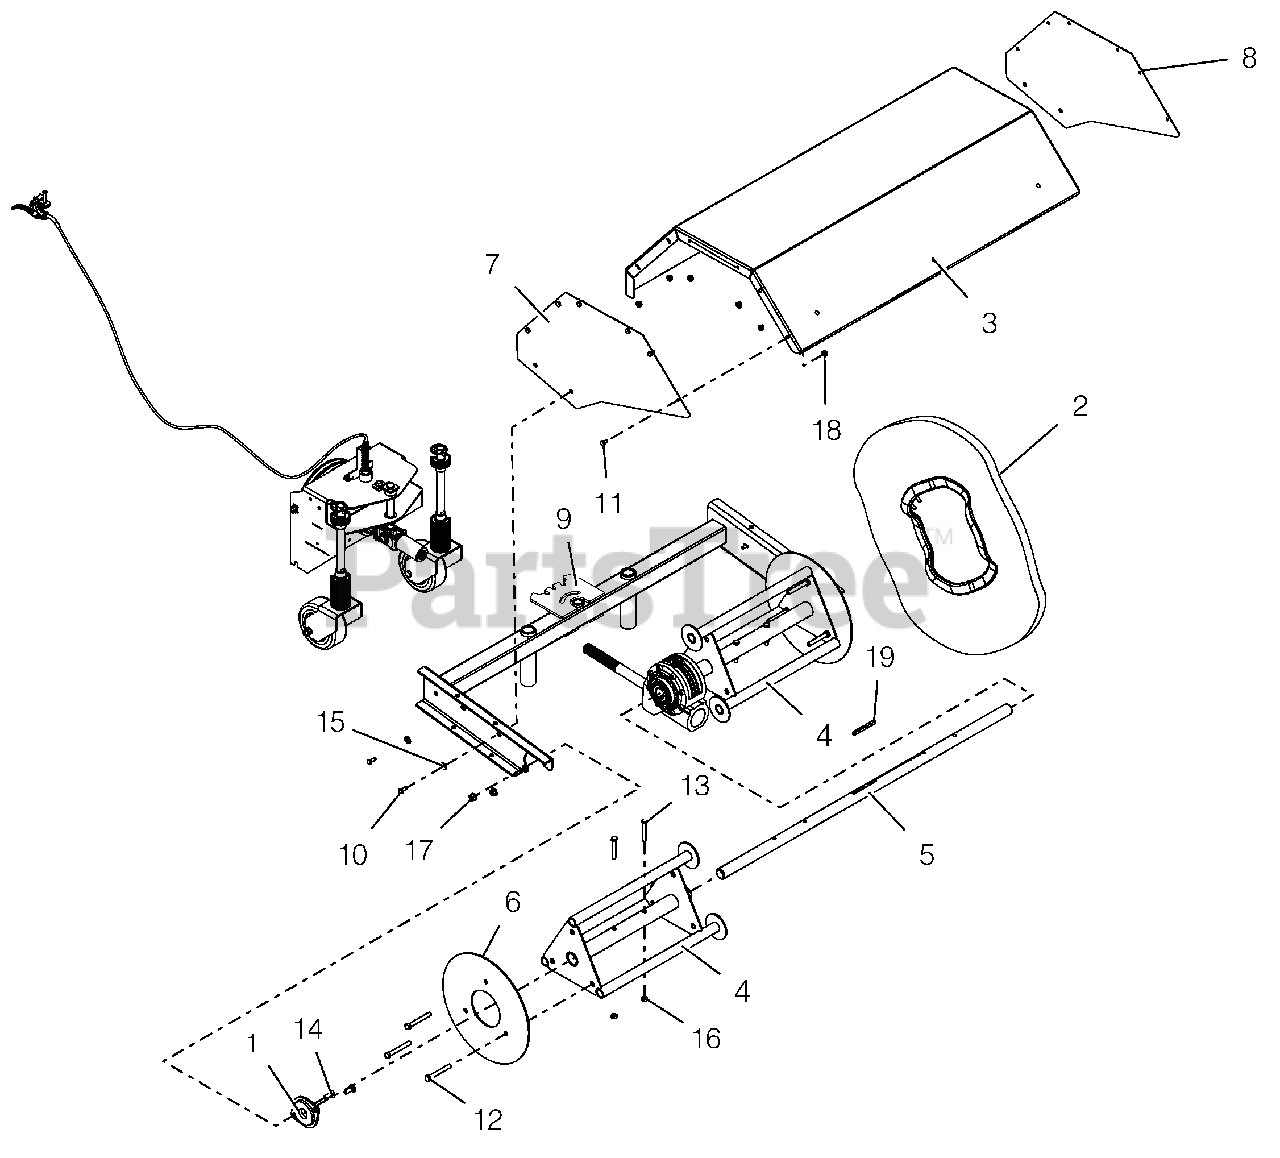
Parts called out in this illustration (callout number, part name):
1	BEARING,2 BOLT FLANGE 1-1/8 ID
2	KIT, BRISTLE - SET OF 18
3	COVER,TOP-36" BRUSH W/DECALS
4	PB36 DRIVE CORE SERVICE KIT
5	CENTER, SHAFT
6	PLATE, END RETAINER
7	WLDT, SIDE COVER - RH
8	WLDT, SIDE COVER - LH
9	FRAME, POWER BROOM 36"
10	@BLT-HEX .25-20X.75 GR5 YWZC
11	@BLT-HEX .25-20X.50 GR5 YWZC
12	BLT-HEX .38-16X3.00 GR5 FTH YZ
13	@BLT-HEX .31-18X2.25 GR5 YWZC
14	@BLT-RDHDSQNK .38-16X1.00 G5YZ
15	@WSHR-FL-STL.312X.734X.065 YWZ
16	@NUT-LK-CTR .31-18 YWZC
17	@NUT-LK-TOP-FLG .38-16 YWZC
18	@NUT-LK-TOP-FLG .25-20 YWZC
19	KEY .25 X .25 X 3IN
